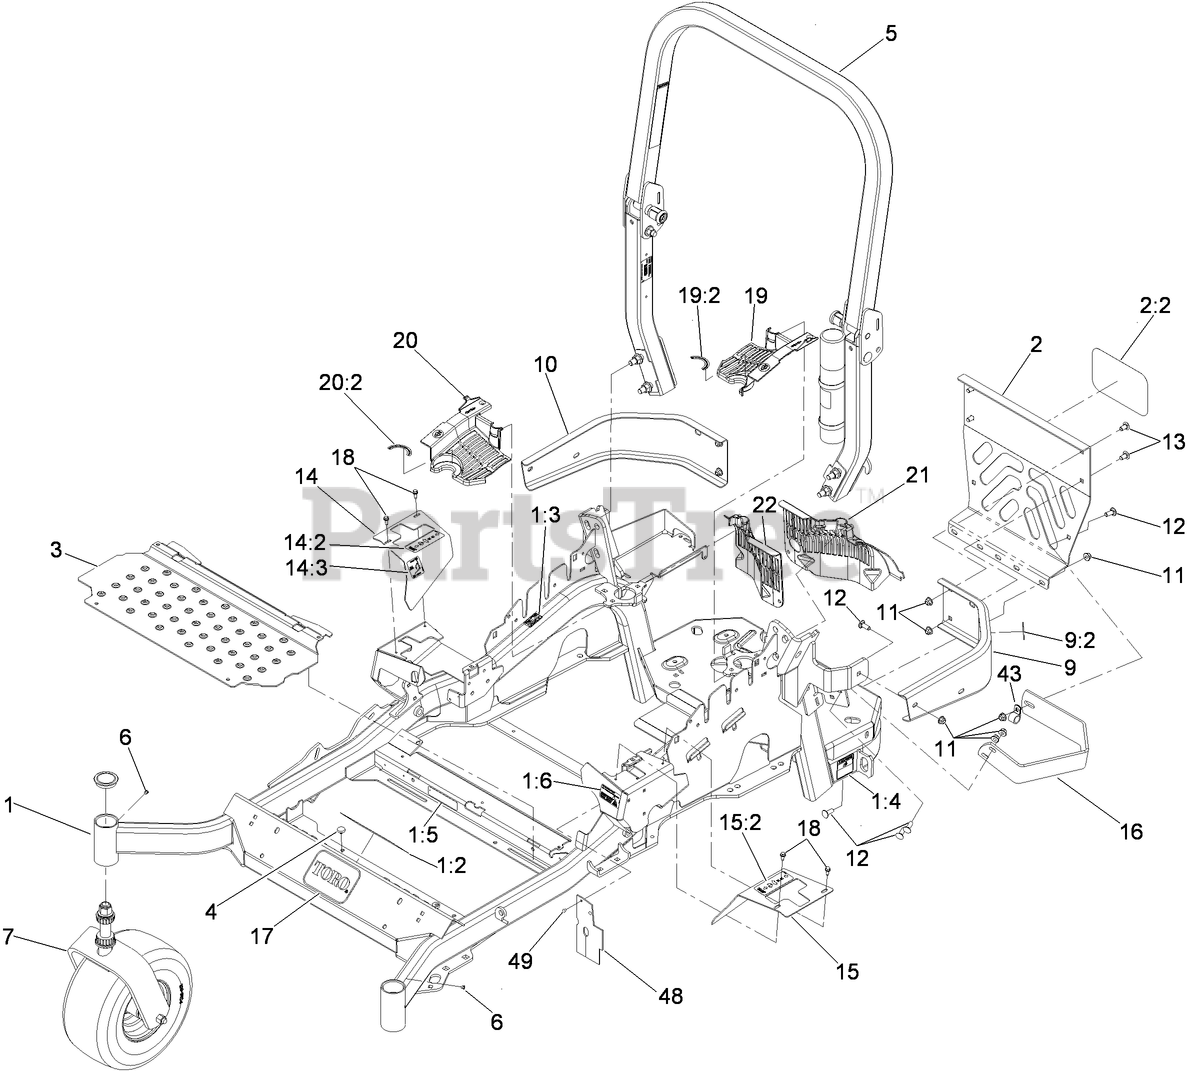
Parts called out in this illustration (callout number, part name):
1	MAIN FRAME ASM
1:2	DECAL-CAUTION
1:3	DECAL-WARNING
1:4	DECAL-BELT DRIVE
1:5	DECAL-ARRESTER, SPARK
1:6	DECAL-FUEL FILL
2	REAR GUARD ASM
2:2	DECAL
3	FLOORPAN
4	BUMPER
5	ROPS ASM
7	Caster Wheel ASM
9	LH BUMPER ASM
9:2	DECAL-CAUTION
10	BUMPER-RH
11	NUT-HF, NI
12	SCREW-CARR
13	SCREW-CARR
14	RH MOTION CONTROL COVER ASM
14:2	DECAL-MOTION CONTROL
14:3	DECAL-PARK BRAKE
15	LH MOTION CONTROL COVER ASM
15:2	DECAL-MOTION CONTROL
16	GUARD-MUFFLER
17	DECAL
18	SCREW-HWH
19	LH HYDRO GUARD ASM
19:2	DECAL-HYDRO OIL
20	RH HYDRO GUARD ASM
20:2	DECAL-HYDRO OIL
21	GUARD-HYDRO, REAR (LH)
22	GUARD-HYDRO, REAR (RH)
43	CLIP-LOOM
48	DEFLECTOR-AIR FLOW
49	RIVET-POP
